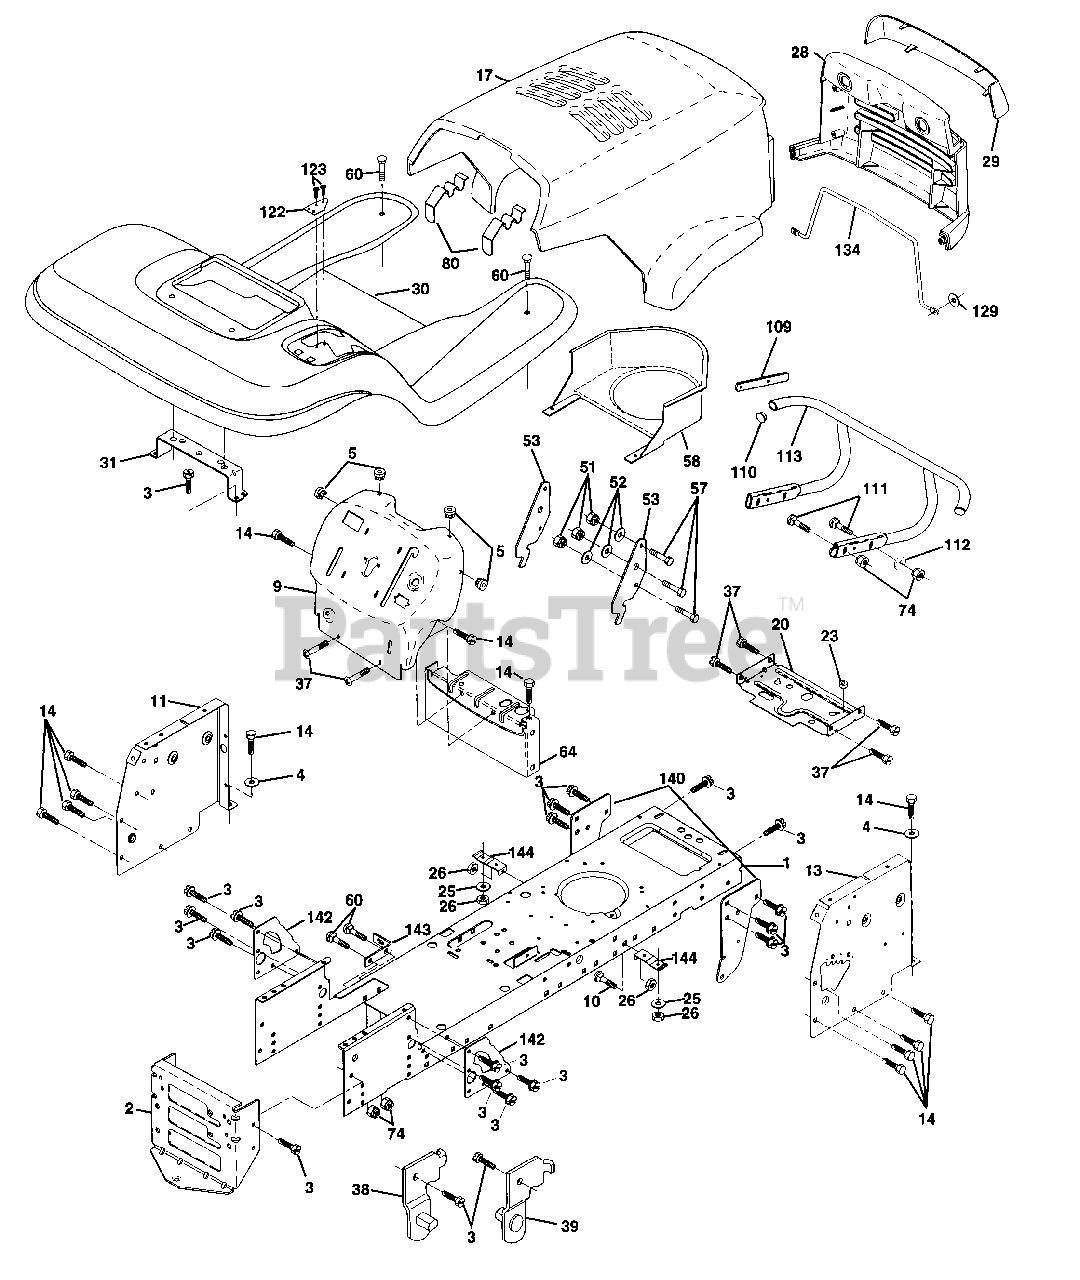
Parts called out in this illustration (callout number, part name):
1	Chassis Weldment
2	Drawbar, Stretch
3	Screw Thdrol 3/8-16 x 3/4 Ty-tt
4	Washer 13/32 x 3/4 x 16 Ga.
5	Bumper Hood/Dash
9	Dash P/L M, N/AMM N/HM Grey
10	Bolt Carriage 3/8-16 x 1
11	Panel Dash Lh
13	Panel Dash Rh
14	Screw Thdrol 3/8-16 x 1/2 Ty-tt
17	Hood LT/PL Husqvarna
20	Plate Mtg Battery Fuel Tank Fr
25	Washer 13/32 x 13/16 x 12 Ga
26	Nut Lock Hex W/Ins 3/8-16 Unc
28	Grille LT/PL Husqvarna
29	Lens LT/PL Husqvarna
30	Fender Footrest STLT Pnt
31	Bracket Support Fender
37	Screw Thdrol 6/16-18 x 1/2 TYT
38	Bracket, Asm. Pivot, L.H., Mower Rear
39	Bracket, Asm. Pivot, R.H., Mower Rear
51	Nut Lock Hex W/Ins 1/4-20
52	Washer 9/32 x 7/8 x 16 Ga.
53	Bracket Pnt. Pick off LT/PL Husqvarna
57	Bolt Hex 1/4-20 x 3/4
58	Air Duct Engine P/L
60	Bolt Rdhd Sqnk 3/8-16unc x 3/4
64	Dash Lower STLT
74	Nut Crownlock 3/8-16 UNC
80	Latch Hood Plm Husqvarna
109	Bracket Extension Bumper
110	Plug Plastic
111	Bolt RDHD 3/8-16 UNC x 1-1/2
112	Washer 13-31 x 13/16 x 16 Ga.
113	Bumper Asm.
129	Washer 9/32 x 5/8 x 16 Ga.
134	Rod Support Hood ET/PL Husq.
140	Bracket Chassis Front 7 Ga.
142	Plate Reinforcement STLT
143	Bracket Swaybar Chassis
144	Bracket Pnt Footrest STLT
146	Screw Torx Hd Thd 5/16-18 UN-2A
